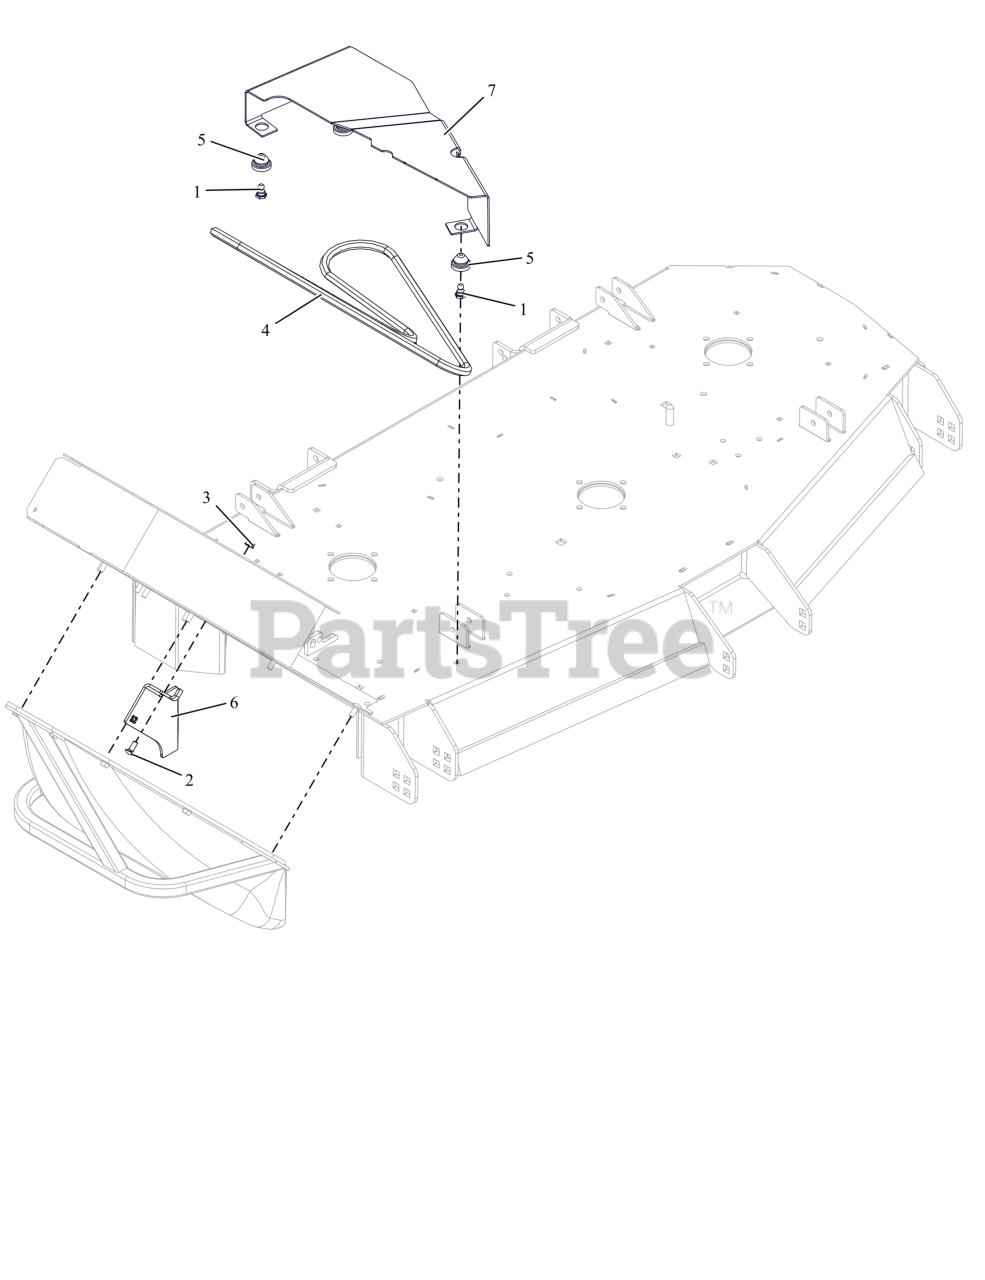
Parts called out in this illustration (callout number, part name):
1	STUD, BALL FEMALE .250-20 THREAD
2	BLT, RHSSN.31-18X.750 G5 ZCC
3	NUT,LK-CTR-FLG .31-18 GF ZCC
4	HEX BELT, HAA SECTION
5	COUPLING, RUBBER PUSH-IN
6	BRKT, PT600 52" BAGGER DISCH (BLACK)
7	GUARD, RH BLOWER DECK BELT (BLACK)
